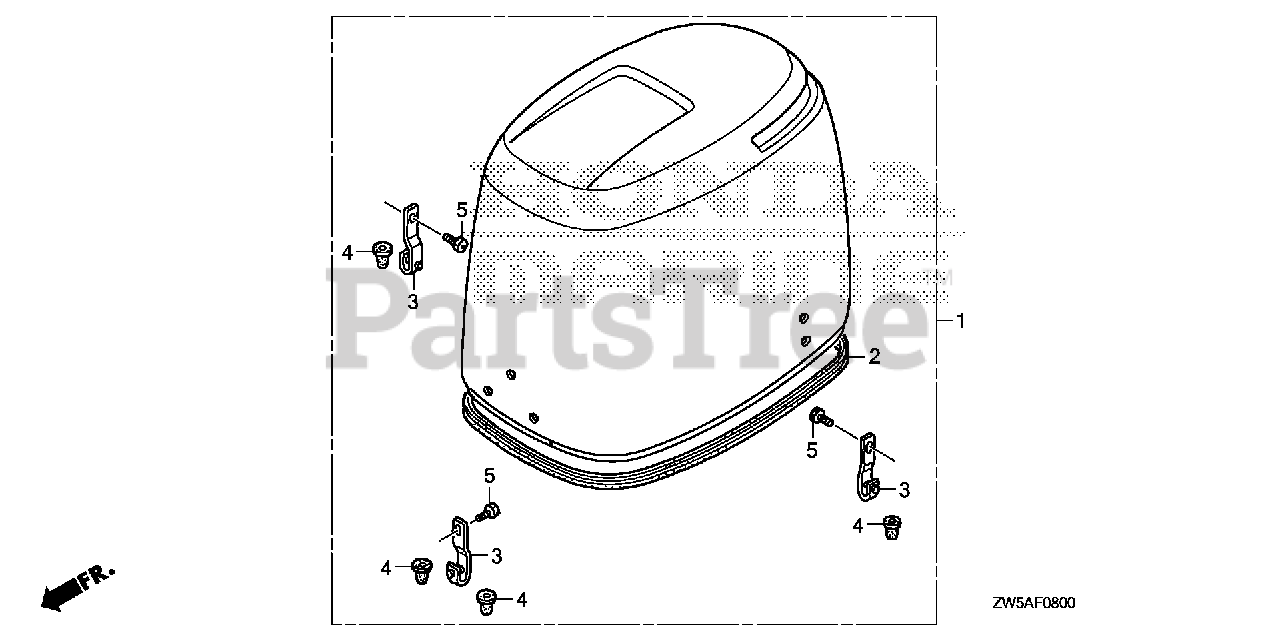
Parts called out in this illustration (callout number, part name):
1	COVER ASSY., ENGINE *NH282MU* (OYSTER SILVER METALLIC-U)
2	SEAL, ENGINE COVER
3	HOOK, ENGINE COVER
4	DAMPER, HOOK
5	BOLT, SOCKET (8X16)
